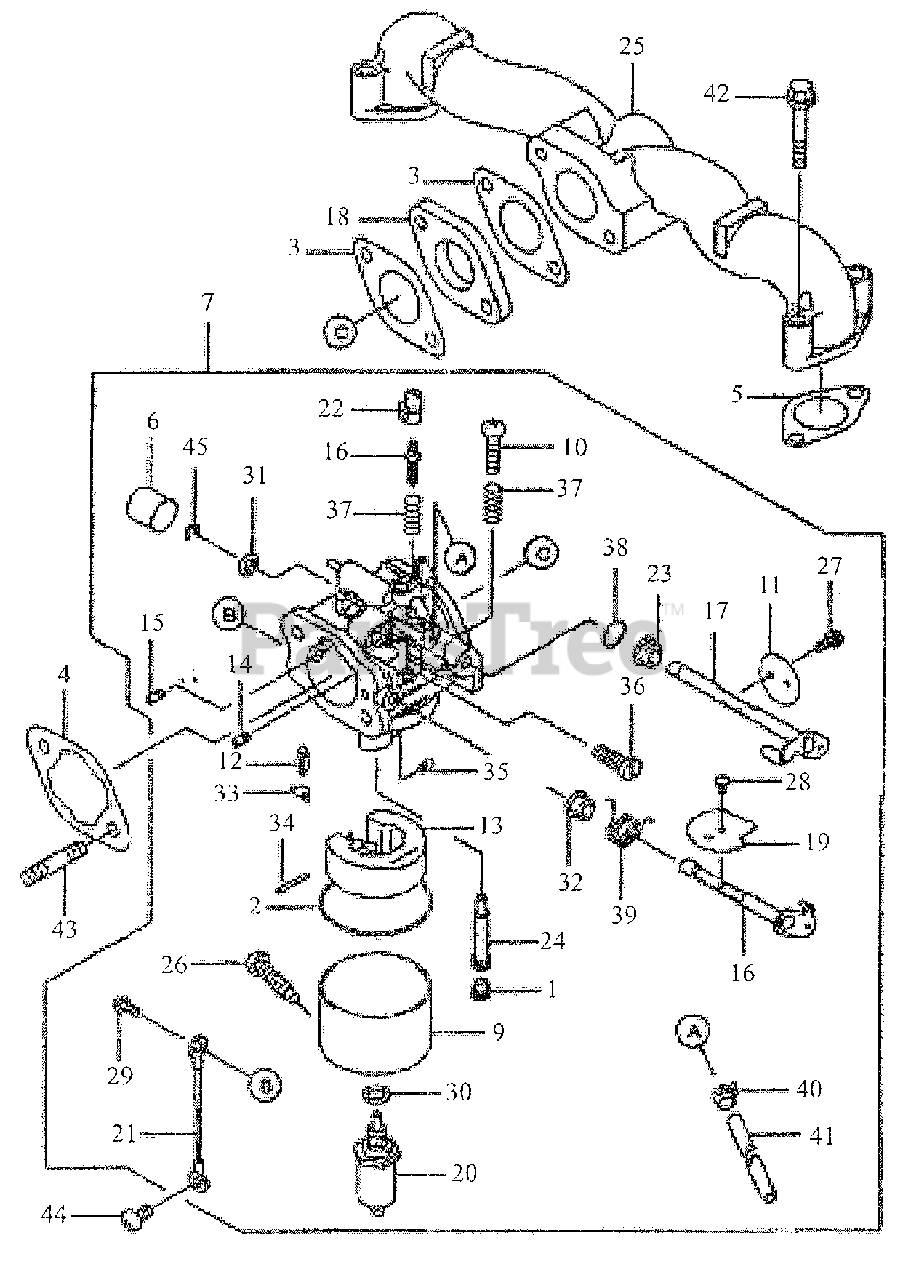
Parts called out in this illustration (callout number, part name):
3	Gasket, Insulator
4	Gasket, Air Filter
5	Gasket
7	Carburetor Assy.
9	Chamber, Float
10	Screw, Throttle Stop
11	Valve, Throttle
14	Jet, Air # 0.8
15	Jet, Air # 2.0
17	Shaft, Throttle
18	Insulator
25	Manifold, Intake
42	Bolt, Flange
45	Circlip, Type E
